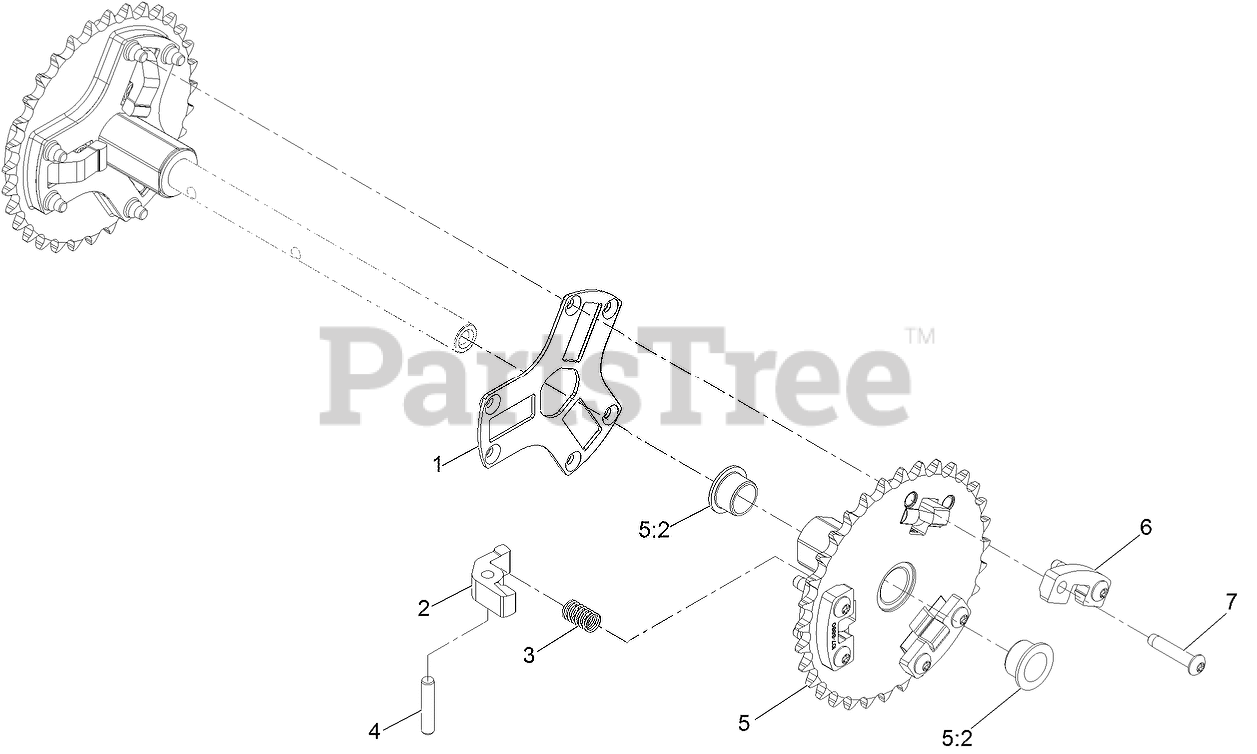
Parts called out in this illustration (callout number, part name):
1	RETAINER-PAWL, PIN
2	PAWL-CLUTCH
3	SPRING-COMPRESSION
4	PIN-DOWEL
5	32T SPROCKET ASM
5:2	BUSHING-FLANGE
6	SUPPORT-PAWL
7	SCREW-TTH, THREAD ROLLING
